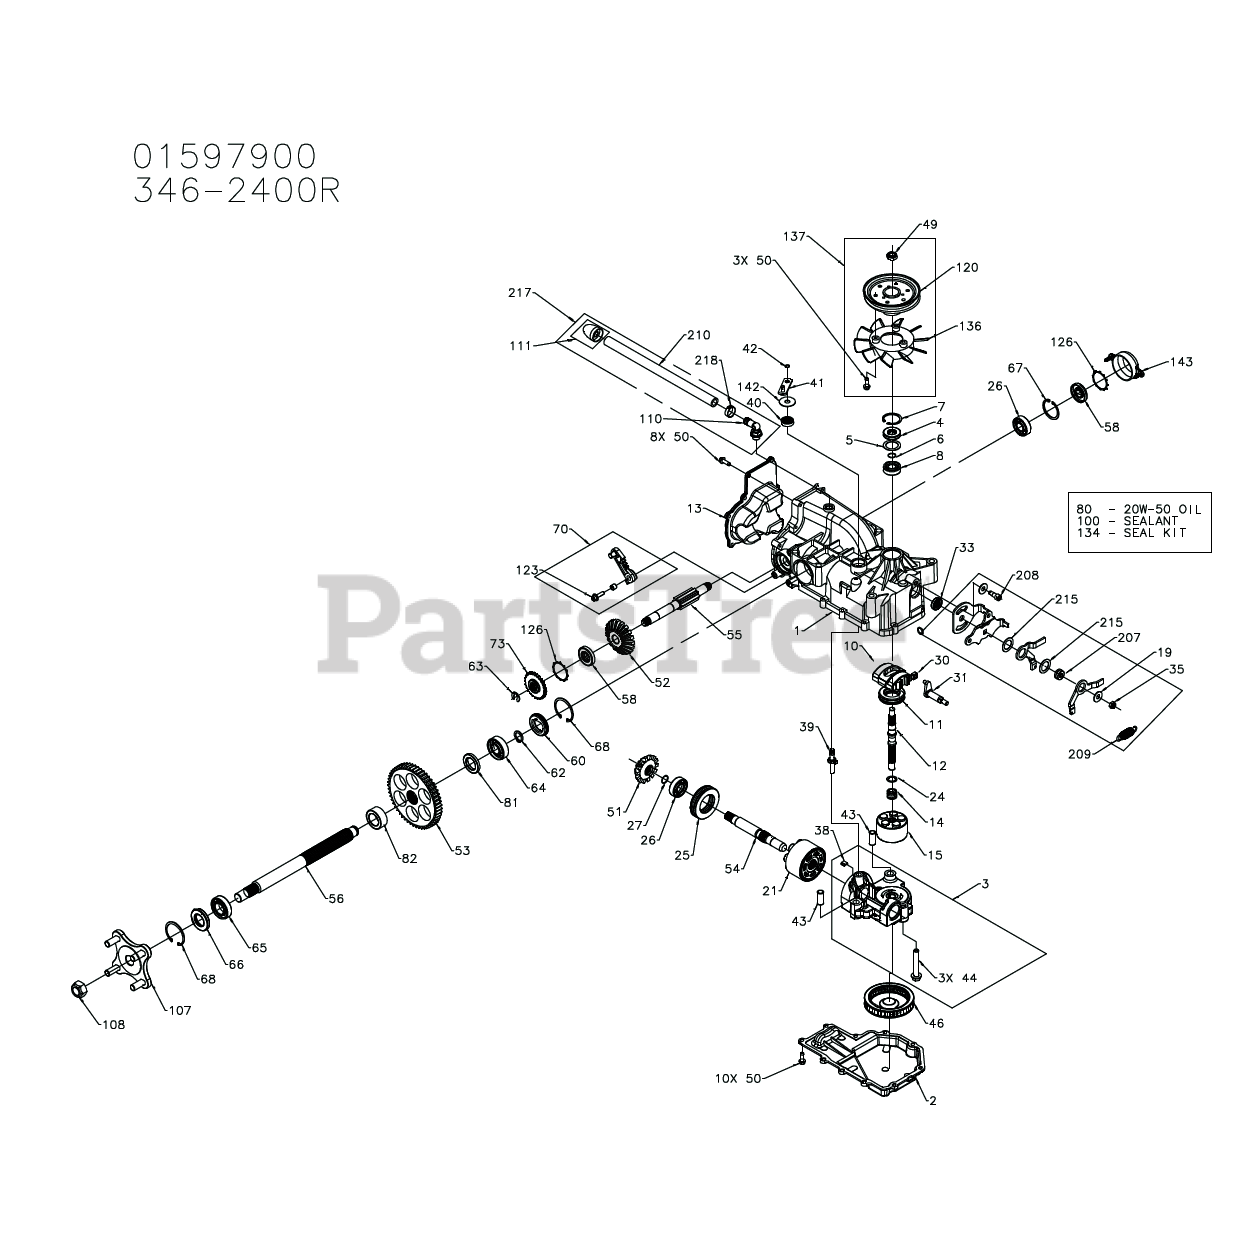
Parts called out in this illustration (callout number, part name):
1	KIT, SHAFT-MAIN HOUSING
2	HSG, IZT LOWER
3	KIT, C-SECTION
4	SEAL, LIP 15X35X7
5	WASHER .98X1.37X.04
6	RING, WIRE RETAINING
7	RING. RETAINING
8	BEARING, SHAFT BALL
10	SWASHPLATE. VARIABLE
11	BEARING. THRUST 30 X 52 X 13
12	SHAFT, INPUT
13	COVER, END IZT
14	SPRING. BLOCK
15	KIT, 10 CC BLOCK
21	ASSEMBLY BLOCK
24	WASHER. THRUST .59 X .79 X .04
25	BRG, THRUST BALL 42X68X16
26	BRG, BALL 17X40X12
27	RING, RET WIRE .561 ID
30	GUIDE. SLOT
31	ARM. TRUNNION TAPERED SQUARE
33	SEAL, LIP 12X25X7
39	ACTUATOR, BYPASS
40	SEAL, LIP
41	ARM. BYPASS
42	RING, RETAINING
50	HFHCS 1/4-20X.75
51	GEAR, BEVEL 14T
52	GEAR, BEVEL 19T
53	GEAR, SPUR 53T
54	SHAFT, MOTOR
55	SHAFT, BRAKE
56	AXLE, 1.0X12.3
58	SEAL, LIP 17X40X7
60	PLUG, SEAL 1.86
62	RING, RET .75 EXT
63	RING, RET .440 EXT
64	BRG, BALL 20X47X14
65	BRG, BALL 25X47X12
66	SEAL, LIP 25X47X7
67	RING, RET 1.56 INT
68	RING, RET 1.87 INT
70	BRAKE ARM,RH IZT
73	BRAKE, PARK SPLINE
80	FLUID, HYDRO 20W50 QT
80	FLUID, HYDRO 15W50 QT
100	SEALANT TUBE 10.1OZ.
107	ASSEMBLY, HUB
126	RING, RET 1.43"
134	KIT, SEAL
137	KIT, FAN/PULLEY
142	WASHER, .392 X 1.250 X .0
143	CAP, BRAKE
207	SPACER, TRUNNION
208	SHCS 5/16-24X.75
209	SPRING, EXTENSION
216	KIT, RTN SCISSOR
217	BREATHER ASSEMBLY
